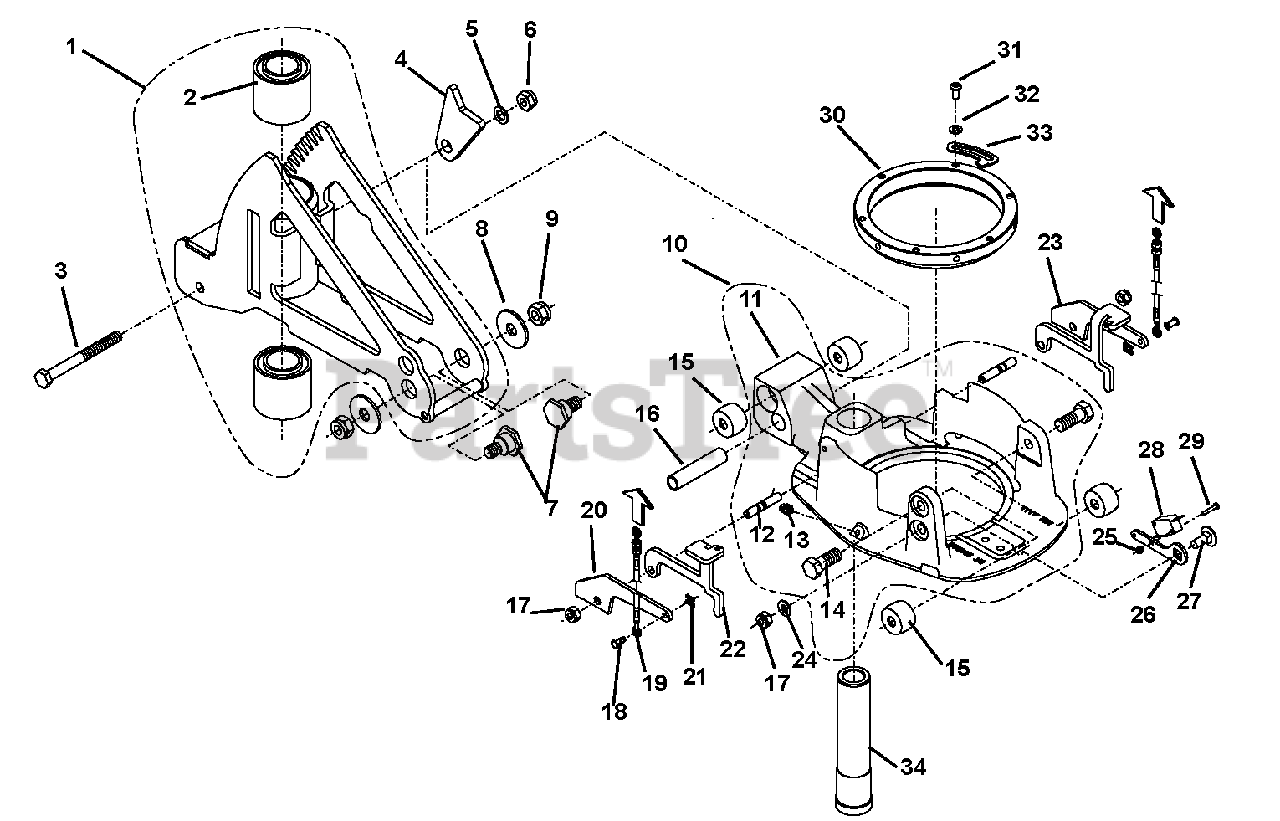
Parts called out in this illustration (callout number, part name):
1	Support Handle
2	Silentbloc
3	Bolt, Hex M10 x 100
5	Washer, 10.5 x 18
6	Nut, Lock D985 M10
8	Washer. 13 x 40 x 3
9	Nut, Lock M12
10	Support, Handle Assembly (Includes 11 - 14)
11	Support Handle
12	Bolt, Stud M8FO x 30
13	Lubricator
14	Bolt, Hex M12 x 30
15	Silentbloc
16	Distance Spacer
17	Nut, Lock, D985 M8
18	Pin, Lock 5 x 12.5 x 10
19	Cable, Steering
21	Washer, Lock
22	Arm, Steering Right
23	Arm, Steering Left
24	Washer, Form S 8.2/16.2 x 1.4
25	Nut, Lock D985 M3
26	Plate, Lock
27	Screw, Truss Head M8 x 25
28	Switch
29	Screw, Slit Head M3 x 18
31	Screw, M6 x 12
32	Washer, Form S 6.1/12.2 x 1.2
33	Washer, Lock
34	Tube, Bearing
